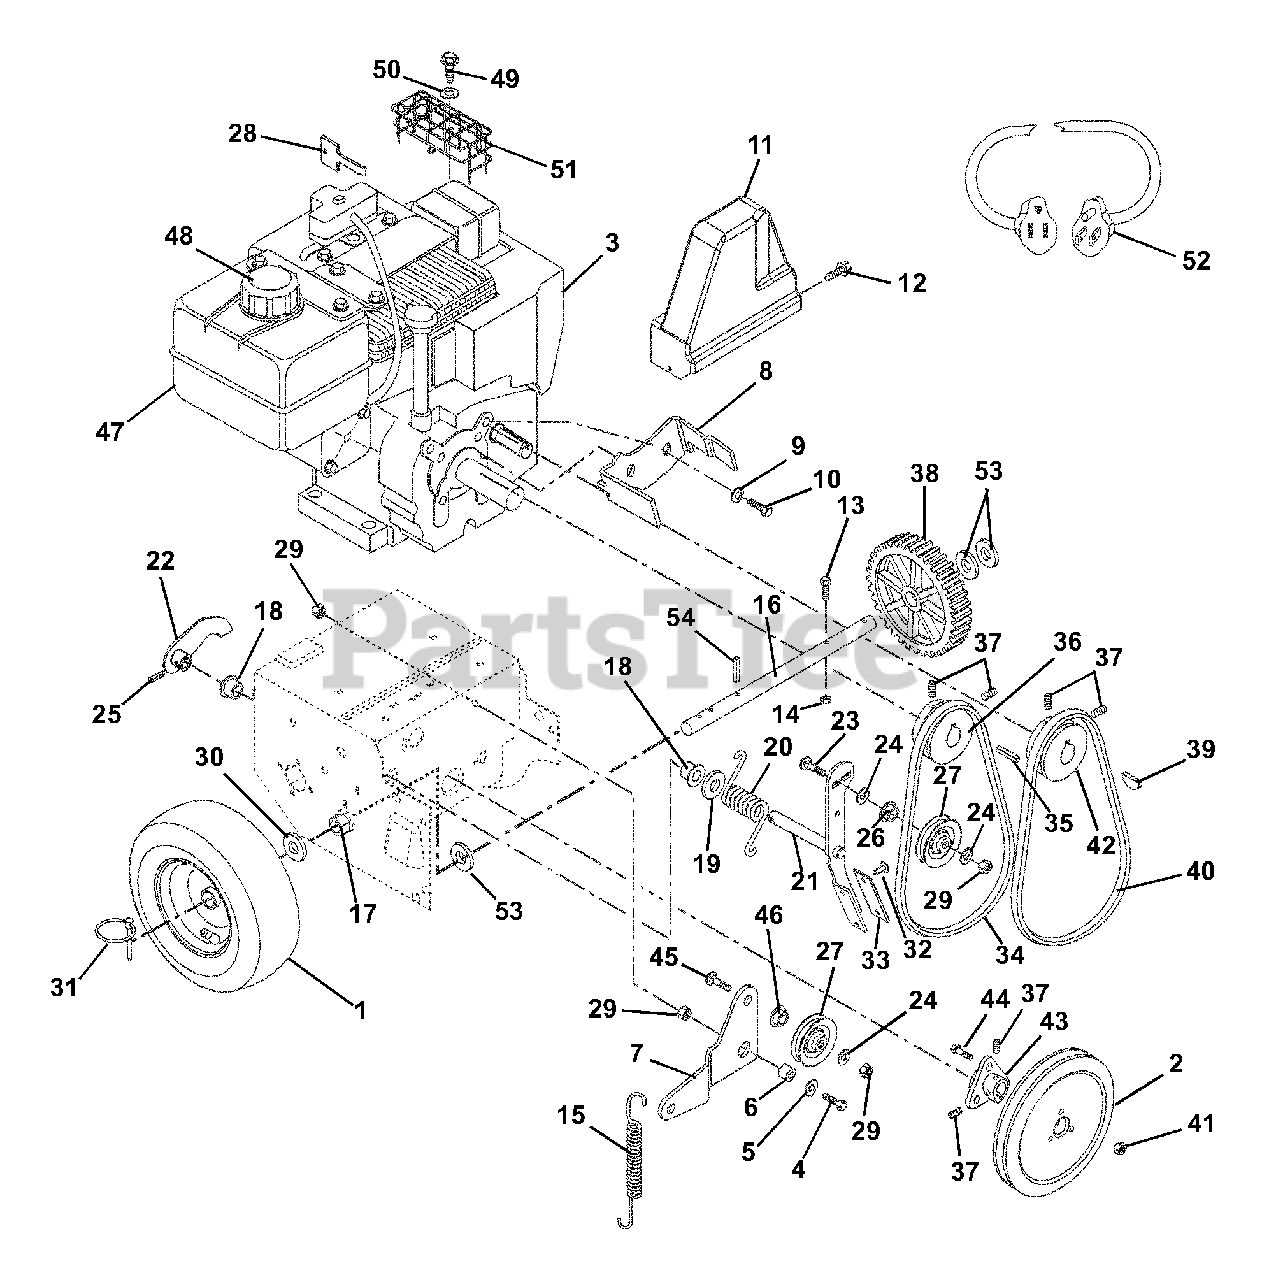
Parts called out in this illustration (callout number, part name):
1	WHEEL 5.00 X 6.00
1	TIRE
1	TIRE/WHEEL ASSY 4.10-6 PIN-LOK
2	PLY-V 8.0 X 1.25 3BLT SALEM
3	ENGINE, TECUMSEH HSSK50 120V
3	ENGINE, 7HP OHV TEC. - 120V
3	ENGINE, TECUMSEH HSSK50
3	ENGINE, 7HP OHV TEC. - RECOIL
4	@BLT-HEX .31-18X.75 GR5 YWZC
5	@WSHR-FL-STL.38X.875X.083 YWZC
6	SPACER BUSHING .5 X .32 X .163
7	IDLER ARM
8	FINGER, BELT
9	@WSHR-LK .31X.078 REG YWZC
10	BLT-HEX .31-24X.75 YWZC GR5
11	COVER, BELT
12	@SCR-TAP .25-20X.37 HWH YWZ TR
13	BLT-HEX .25-20X1.75 GR8 YWZC
14	@NUT-LK-CTR .25-20 YWZC
15	SG-TENS .047X.44X3.37 WLD 1.47
16	AXLE SHAFT
17	BSHG-FLG .750X.873HEXX.53X1.18
18	BSHG-FLG.500X.625X.312X.750NY
19	WSHR-FL-STL .520X.810X.033YWZC
20	SG-TORS .148X1.0X1.53
21	CLUTCH ARM W/BRAKE PAD
22	ARM-CLUTCH
23	@BLT-RDHDSQNK .31-18X1.25 G5YZ
24	@WSHR-FL-STL.38X.875X.083 YWZC
25	PIN-ROLL .156X.88
26	SPCR, BRG .315X.50X.688X.281
27	IDLER
28	KEY, PUSH/PULL - TECUMSEH
29	@NUT-LK-CTR .31-18 YWZC
30	WSHR-FL-STL.754X1.125X.062YWZC
31	PIN-LOK .31X1.75
32	RVT-TBLR .187X.437 RH ST PL
33	BRAKE LINING
34	BELT,4L TO BE REPLACED07200021
34	V-BELT, 4L-RAW EDGE
35	KEY-SQ .188X1.0X.188 SAE 8630
36	SHEAVE-ENGINE
36	SHEAVE - ENGINE
37	SCR-SET .31-18X.38 SKHCUPDL
39	KEY-WDRF .125X.625X.250 SAE5
40	V-BELT, 3L-COGGED
41	@NUT-SPNLK-FLG .312-18 YWZC
42	SHEAVE - CAMSHAFT
44	BLT-SERRDHD SL .31-18X.75 YZ
45	BLT-RDHDSQNK .31-18X1.0 SHTYZ
46	BSHG, FLG .325X.499X.26X.88
47	PLUG, SPARK
48	CAP, FUEL - TECUMSEH
49	SCR-TAP 10-16X.75 YWZC
50	@WSHR-FL-STL.219X.50X.049 YWZC
51	MUFFLER GUARD 5 HP
52	CORD, ELECTRIC START CORD 120V
53	WSHR-FL-STL .755X1.25X.125 YZ
54	PIN-ROLL .188X1.25
